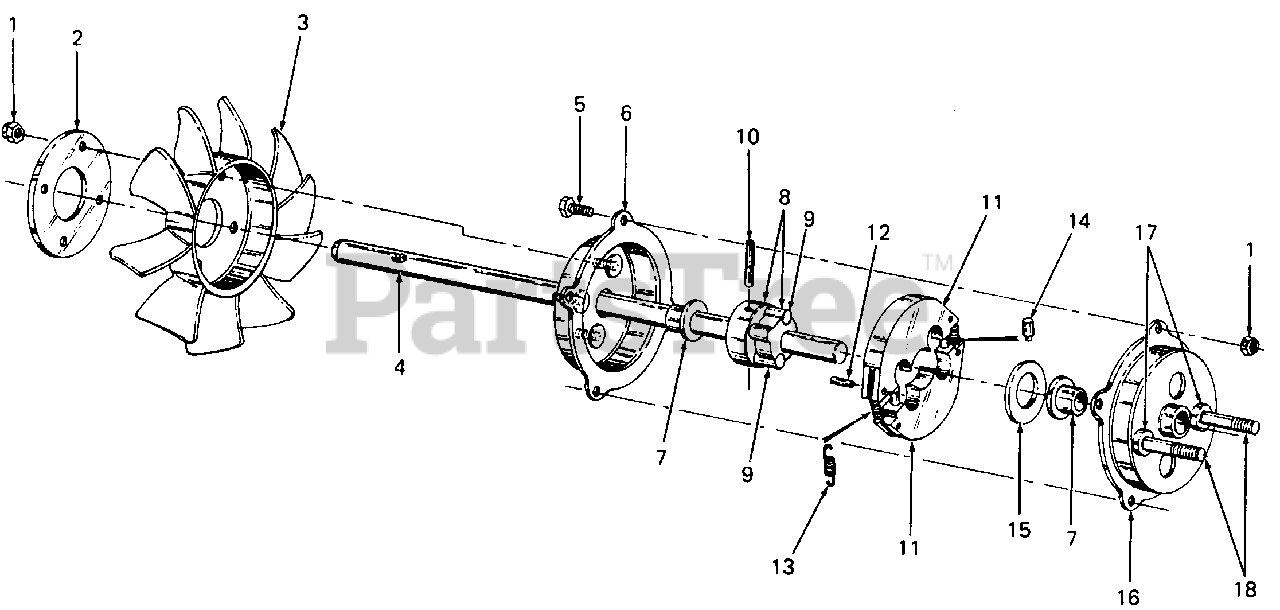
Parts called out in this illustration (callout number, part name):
1	Nut, Hex Patch Lock, 1/4-20
2	Spacer, Fan
3	Fan, Cooling
4	Shaft, Drive
5	Screw, Hex Cap, 1/4-20 X .50 Lg GR5
6	Cover Assy, Clutch
7	Bearing, Flange
8	Hub Assy, Clutch
10	Pin, Slotted Roll, 1/4 Dia X 2.25 Lg
11	Shoe Assy, Clutch
12	Pin, Spirol Spring, 1/8 Dia X 5/8 Lg
13	Spring, Extension, .31 Dia X .85 Lg
15	Washer, Flat, .760 X 1.49 X .06 Thk HDN
16	Housing, Clutch
17	Spacer, .385 X .88 X .25 Lg
18	Bolt, Ribbed Neck, 3/8-24 X 1.5 Lg GR5
